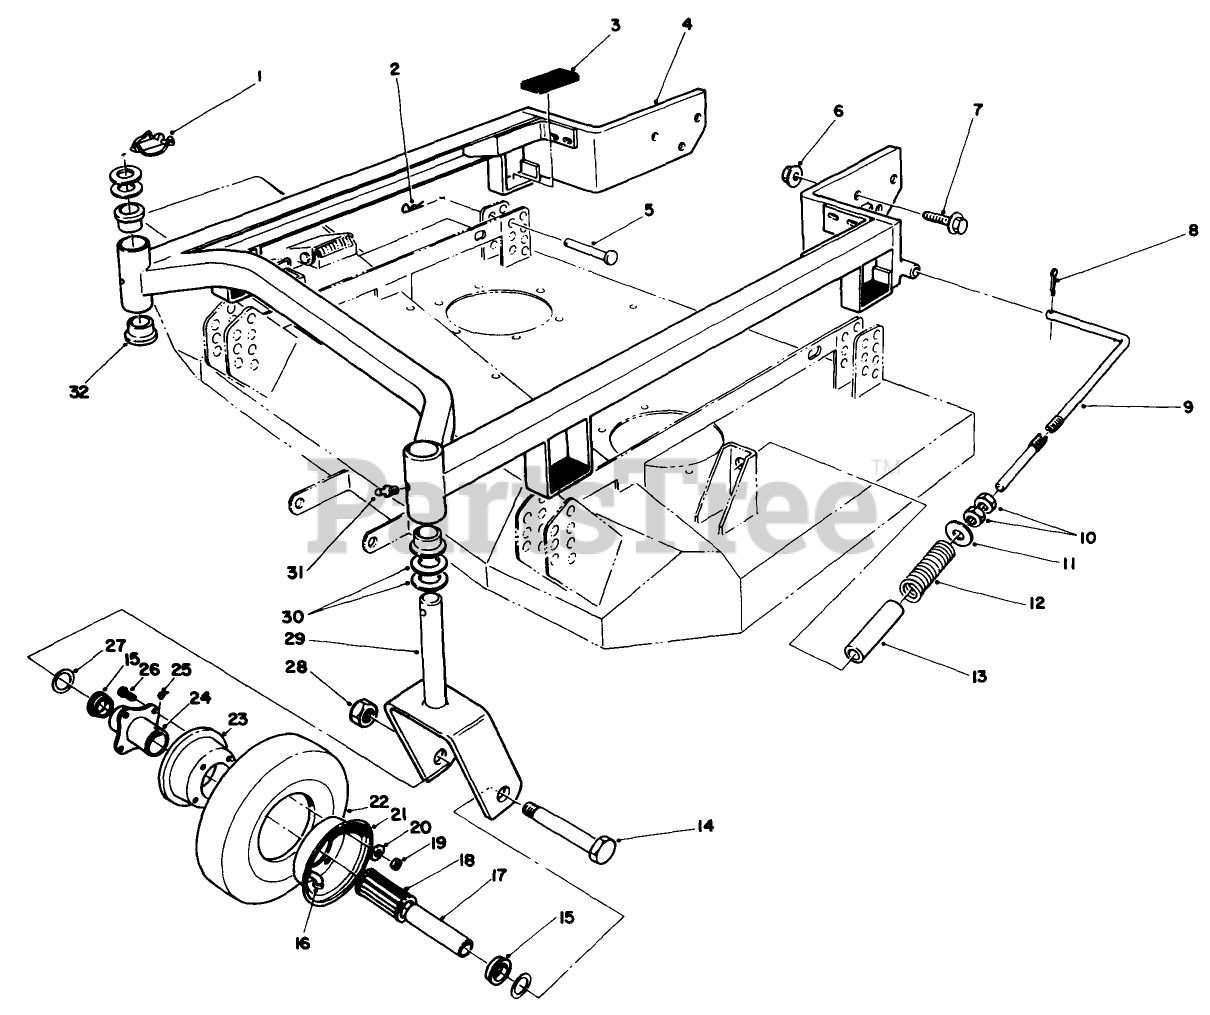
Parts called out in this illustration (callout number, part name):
1	PIN-LYNCH
2	PIN-HAIR
5	PIN-CLEVIS
6	NUT-LOCK, FLANGE
7	SCREW-HHF
8	PIN-COTTER
10	NUT-JAM
11	WASHER
12	SPRING-COMPRESSION
14	SCREW-HH
15	RETAINER
18	ROLLER BEARING
19	NUT-HEX
20	WASHER-LOCK
21	WHEEL HALF-FEMALE
22	TIRE 8"(4-PLY)
23	WHEEL HALF-MALE
24	HUB - CENTERED
25	FITTING-GREASE
26	WHEEL BOLT
27	WHEEL SPACER
28	NUT-LOCK
30	WASHER-THRUST
31	FITTING-GREASE
